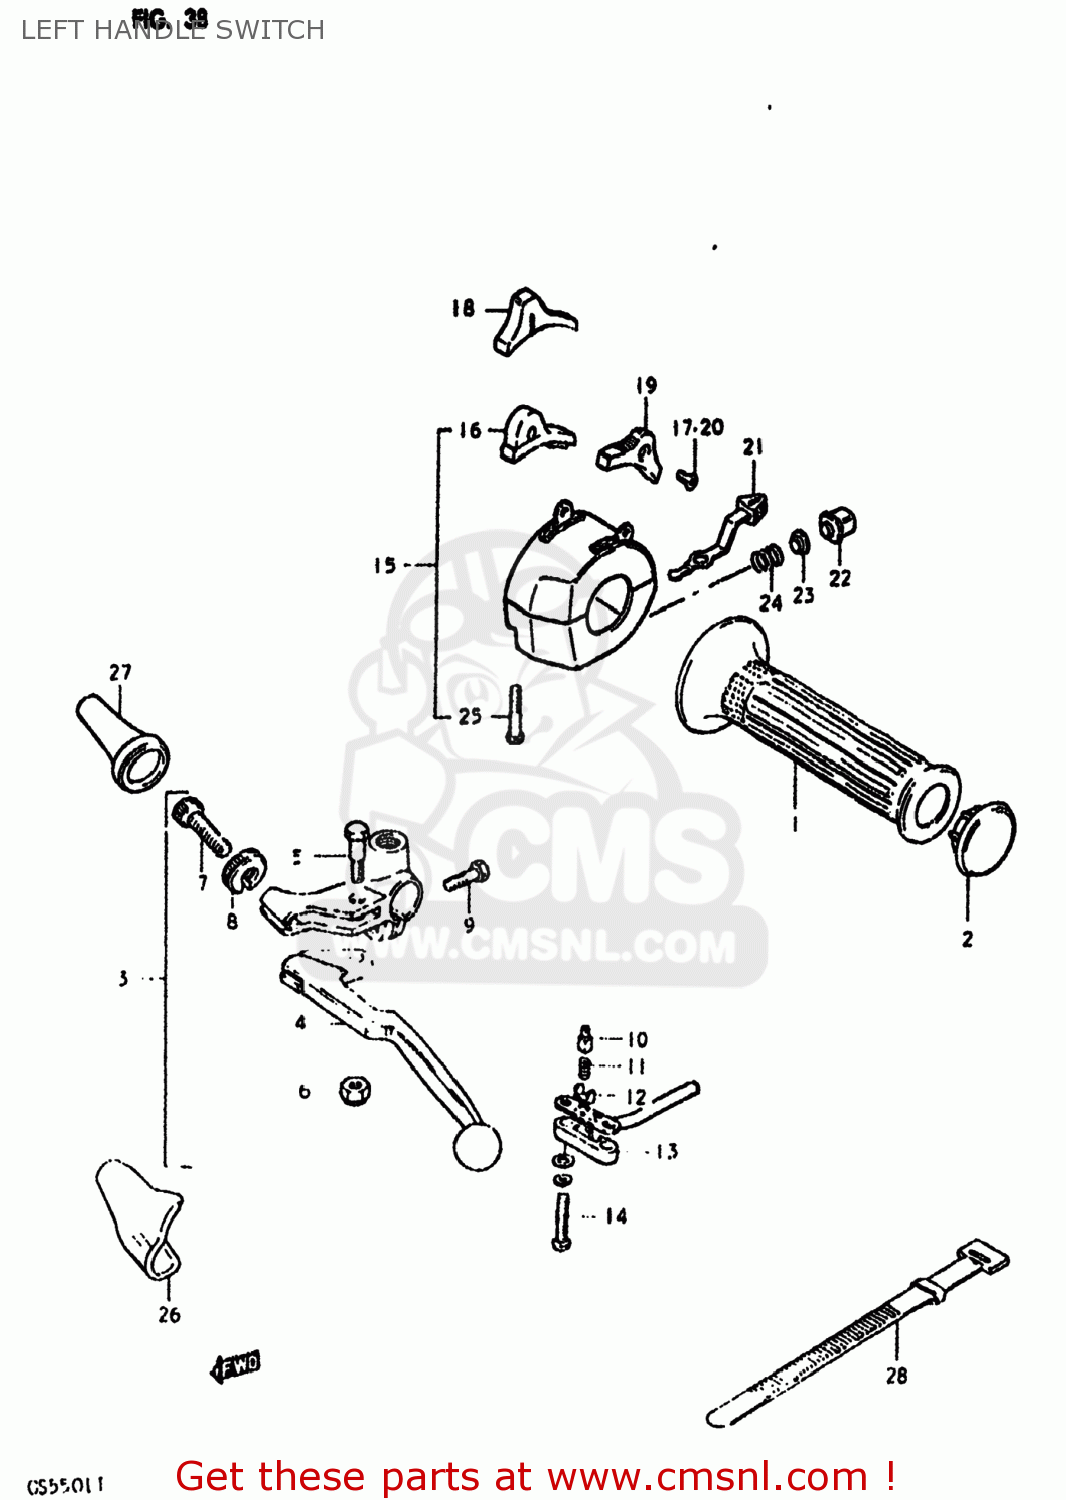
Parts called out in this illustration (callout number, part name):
1	GRIP,LEFT
2	CAP,GRIP END
3	LEVER ASSEMBLY
4	LEVER,CLUTCH
5	BOLT,LEVER
6	NUT 6MM
7	ADJUSTER,CABLE
8	NUT,CABLE ADJUSTER
9	BOLT,CLUTCH LEVER HOLDER
10	HOLDER
11	SPRING
12	PLATE
13	COVER,FR BK TERMINAL BASE
14	SCREW
15	SWITCH ASSY,HANDLE,L
16	KNOB,STOP
17	SCREW
18	KNOB,LIGHTING SWITCH
19	KNOB,DIMMER SWITCH
20	SCREW
21	KNOB,TURNSIGNAL
22	BUTTON,HORN
23	CONTACT
24	SPRING
25	SCREW
26	COVER,CLUTCH LEVER
27	BOOT,CLUTCH CABLE
28	CLAMP(L:120)
